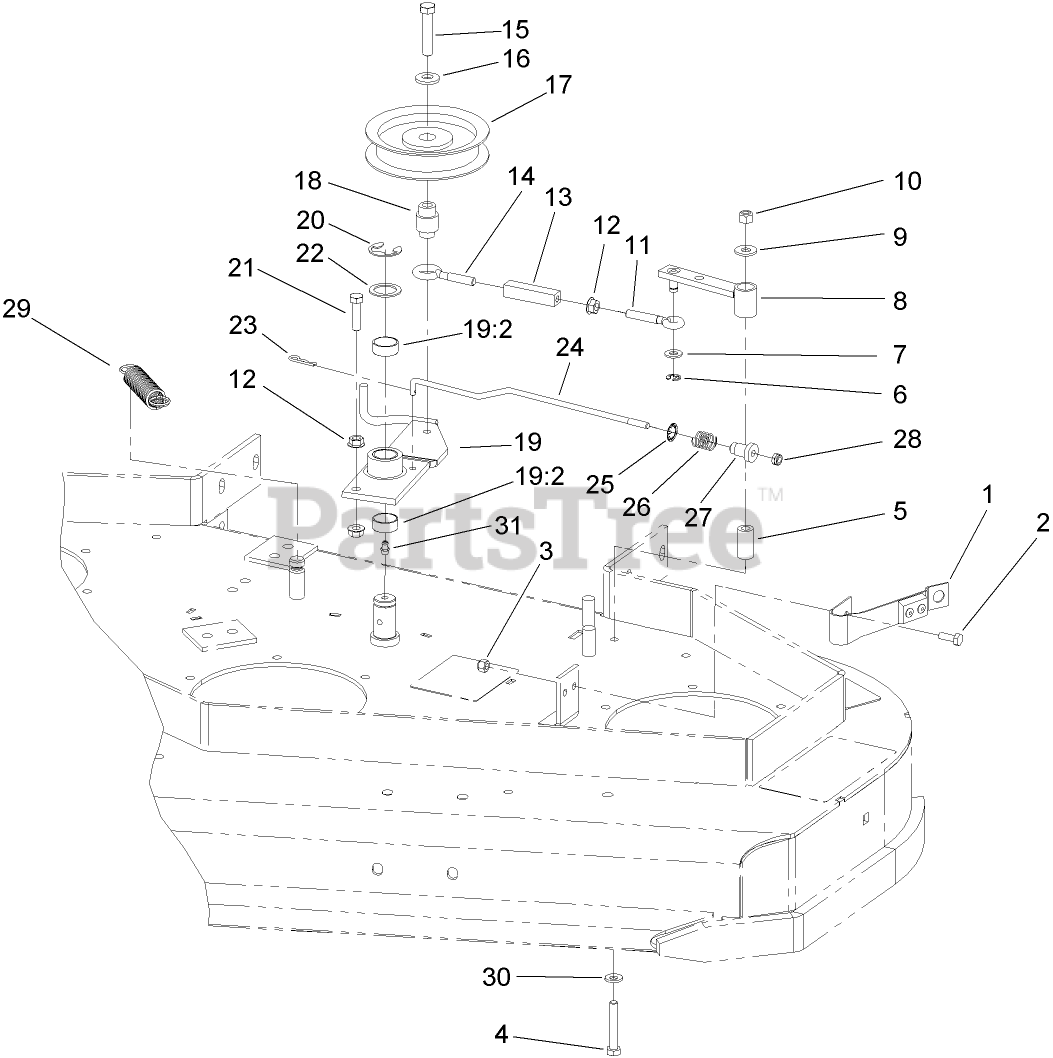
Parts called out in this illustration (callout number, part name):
1	PAD AND SPRING ASM
2	SCREW-HH
3	NUT-LOCK, NI
4	SCREW-HH
5	TUBE-PIVOT
6	RING-RETAINING, EXT
7	WASHER-PLAIN
8	ARM-ASSIST
9	WASHER-FLAT
10	NUT-LOCK, NI
11	EYEBOLT-THREAD, RH
12	NUT-HF
13	BODY-TURNBUCKLE
14	EYEBOLT-THREAD, LH
15	SCREW-HH
16	WASHER-BELLEVILLE
17	PULLEY-IDLER
18	BUSHING-ENGAGEMENT
19	Idler Arm ASM
19:2	SLEEVE-BEARING
20	RING-RETAINING, EXT
21	SCREW-HH
22	WASHER-SPINDLE
23	PIN-COTTER
24	ROD-BRAKE
25	RING-PUSH ON
26	SPRING-COMPRESSION
27	SPACER-FLANGED
28	NUT-LOCK, NI
29	SPRING-EXTENSION
30	WASHER-SPRING
31	FITTING-GREASE
